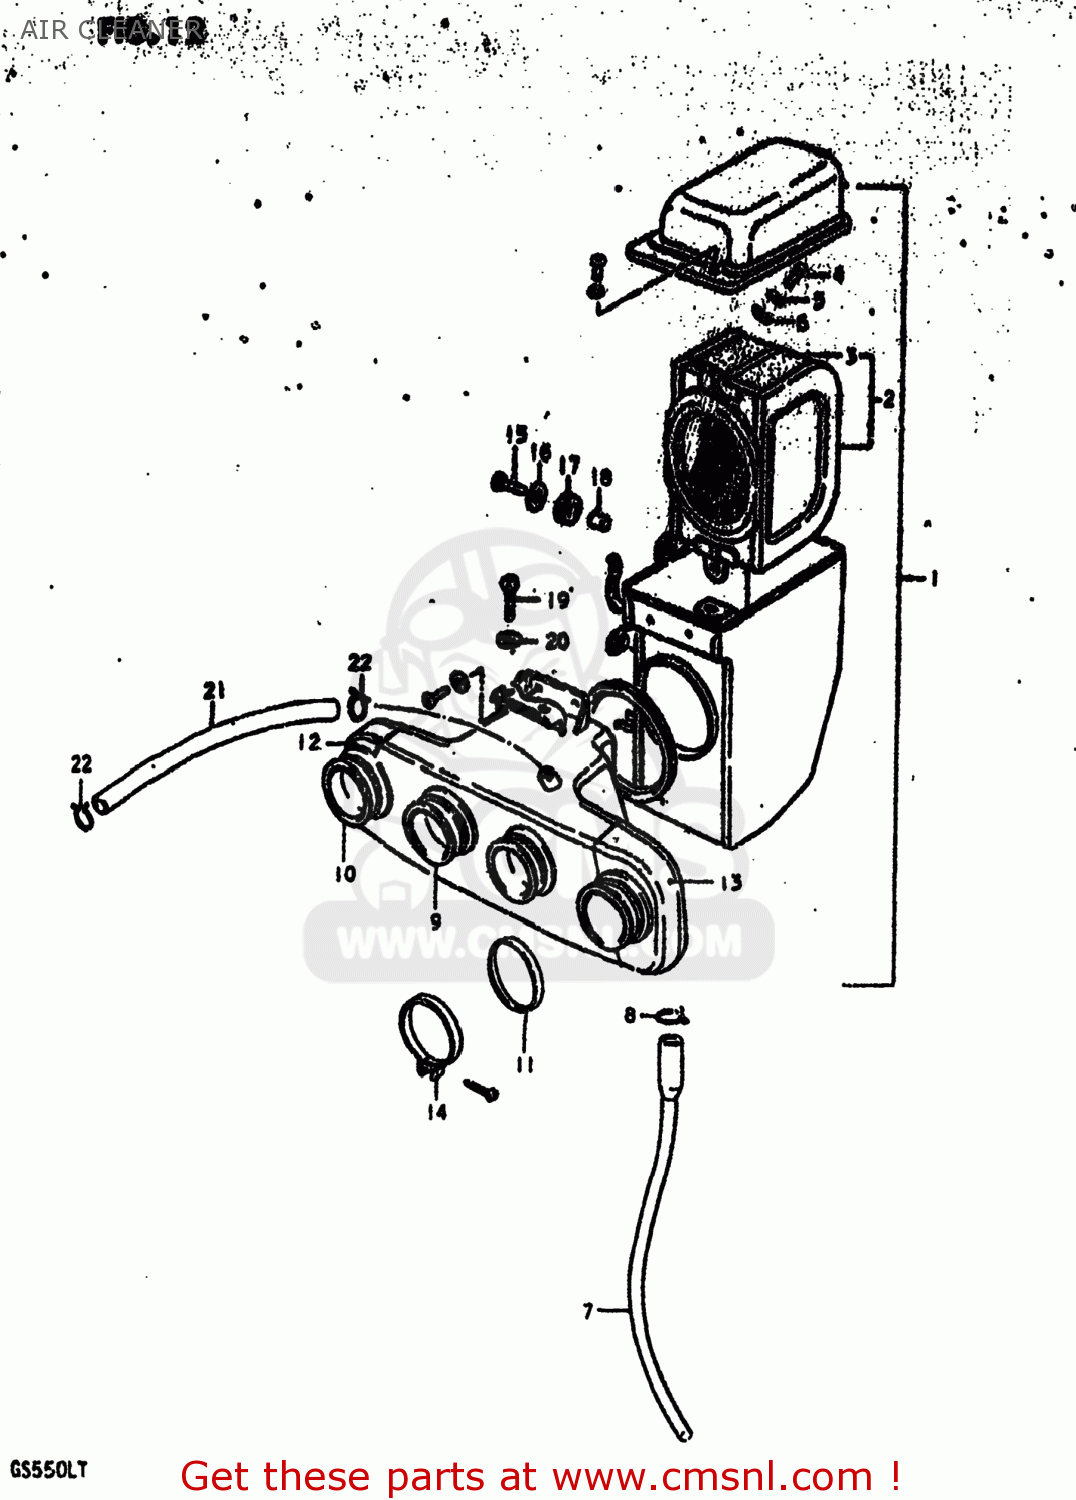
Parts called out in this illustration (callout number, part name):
1	CLEANER ASSEMBLY,AIR
2	FILTER ASSY
3	FILTER
4	SCREW
5	LOCK WASHER
6	WASHER
7	HOLDER,FILTER
8	CLIP
9	TUBE,AIR CLEANER OUTLET A
10	TUBE,AIR CLEANER OUTLET B
11	RING,CARBURETOR AIR INLET HOSE
12	COVER,AIR CLEANER,RIGHT
13	COVER,AIR CLEANER,LEFT
14	CLAMP
15	BOLT
16	WASHER
17	CUSHION
18	SPACER (6.1X9X9)
19	SCREW
20	WASHER
21	HOSE
22	CLIP
